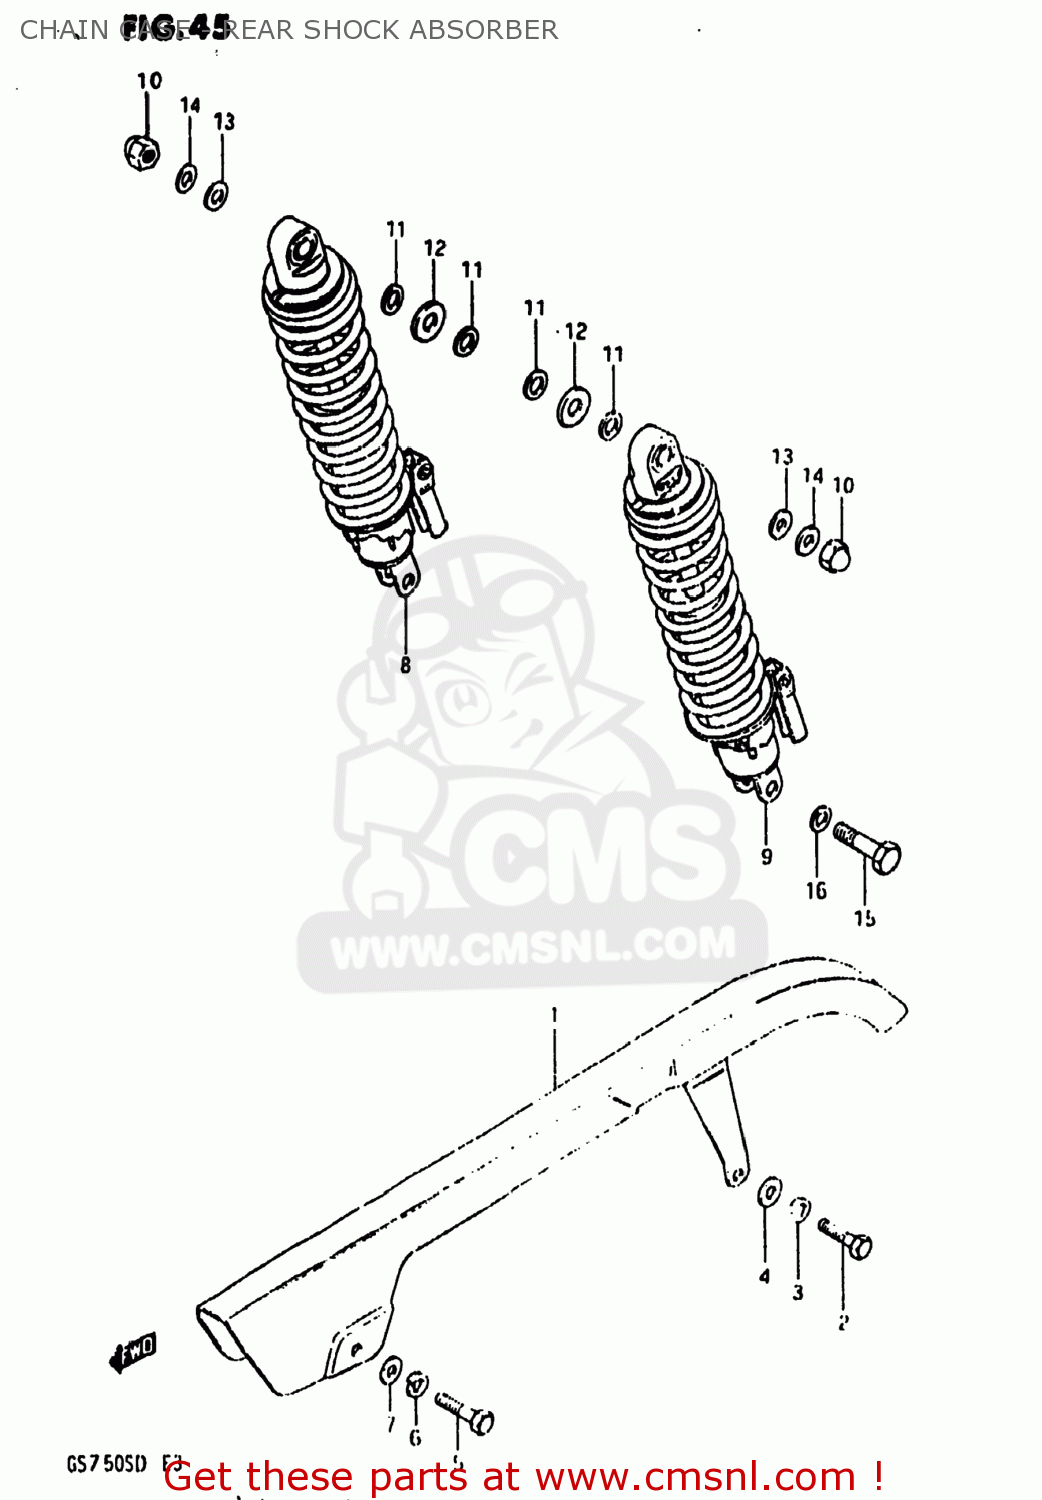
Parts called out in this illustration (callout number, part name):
1	CASE,CHAIN
2	BOLT
3	LOCK WASHER
4	WASHER
5	BOLT
6	LOCK WASHER
7	WASHER
8	ABSORBER ASSEMBLY,REAR SHOCK
9	ABSORBER ASSEMBLY,REAR SHOCK
10	NUT, LOWER LH
11	WASHER
12	WASHER (12.5X24X3.2)
13	WASHER
14	WASHER(10.5X24X3.2)
15	BOLT(10X36)
16	WASHER
